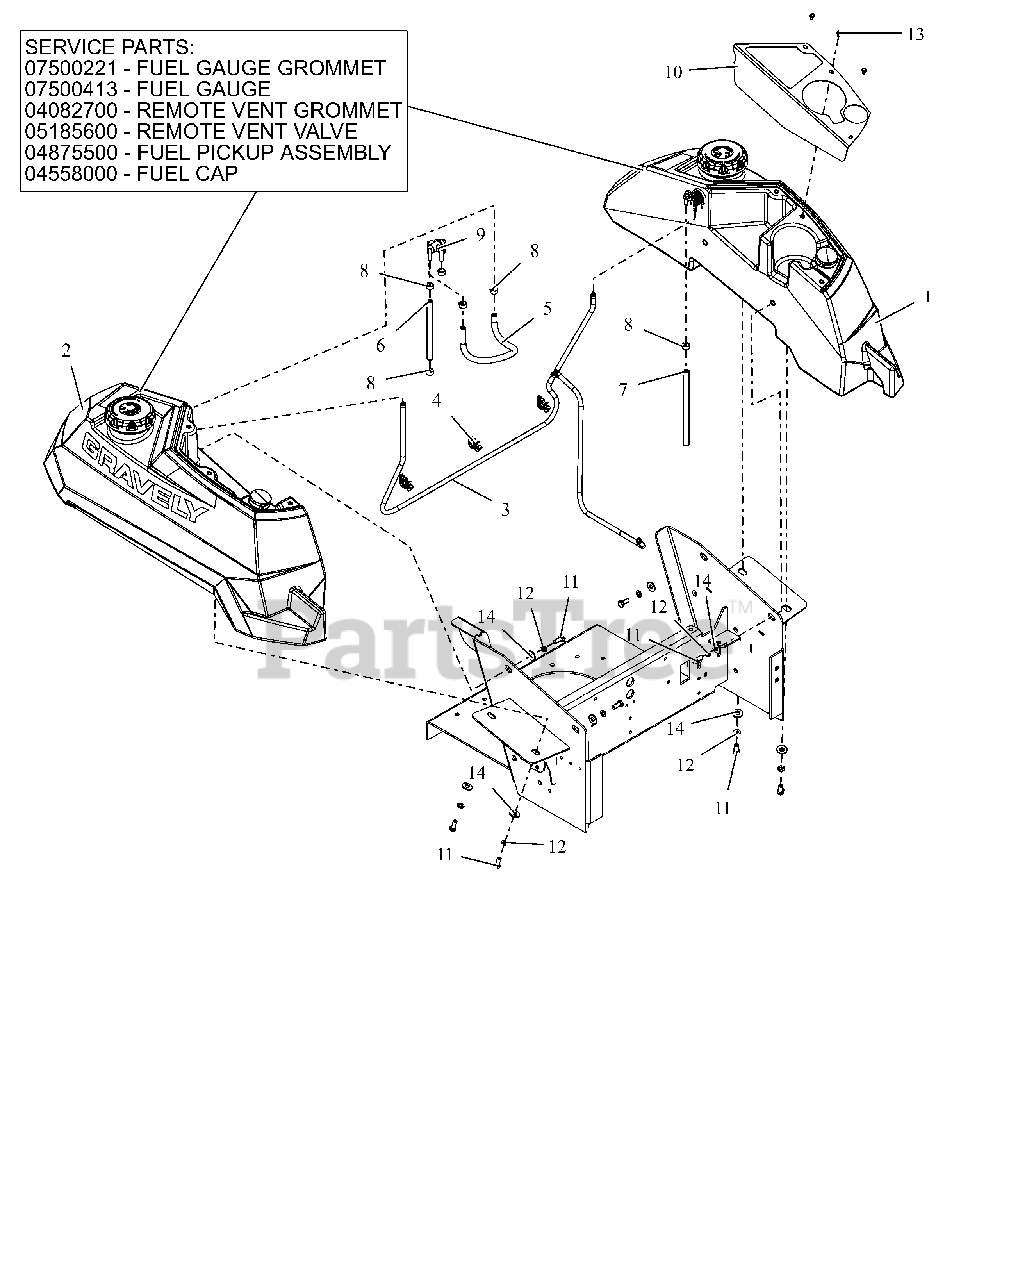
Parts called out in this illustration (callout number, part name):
1	ASM, LH - PT100 FUEL TANK
2	ASM, RH - PT100 FUEL TANK
2	GROMMET, FUEL GAUGE
2	GAUGE, REMOTE SEALED FUEL
2	GROMMET, REMOTE VENT NITRILE
2	VALVE, COMBINATION VENT 3/16
2	ASSM,LRG TANK FUEL PICKUP LINE
2	CAP, FUEL VENTIN AUTOLOCK
3	ASM, VAPOR LINE
4	WIRE CLIP
5	HOSE, .25 LOW-PERM BULK GAS
6	HOSE, .25 LOW-PERM BULK GAS
7	HOSE, .25 LOW-PERM BULK GAS
8	CLAMP, FUEL LINE
9	VALVE, FUEL
10	PT100 CUPHOLDER PANEL - RED
11	@BLT-HEX .31-18X.75 GR5 YWZC
12	@WSHR-LK .31X.078 REG YWZC
13	SCR-MCH 10-24X.38 HWHSTAINLESS
14	@WSHR-FL-STL.38X.875X.083 YWZC
